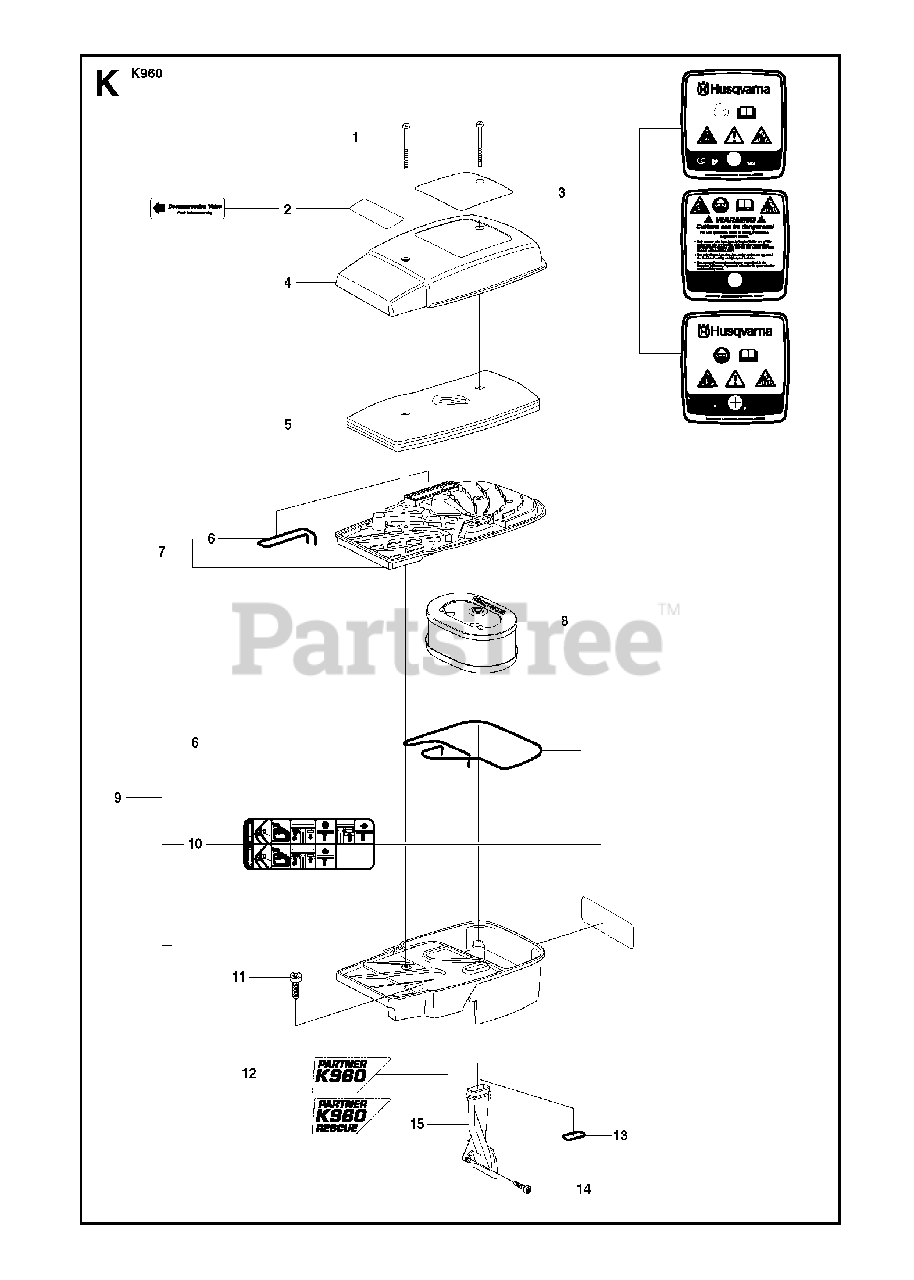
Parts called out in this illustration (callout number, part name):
1	SCREW ITXSCM
3	LABELEPA USA
4	COVER
7	FILTER BOTTOMIncl. 6
9	CYLINDER COVER ASSYIncl. 6, 10
11	SCREW ITXSCM
12	LABEL
14	SCREW ITXSCM
